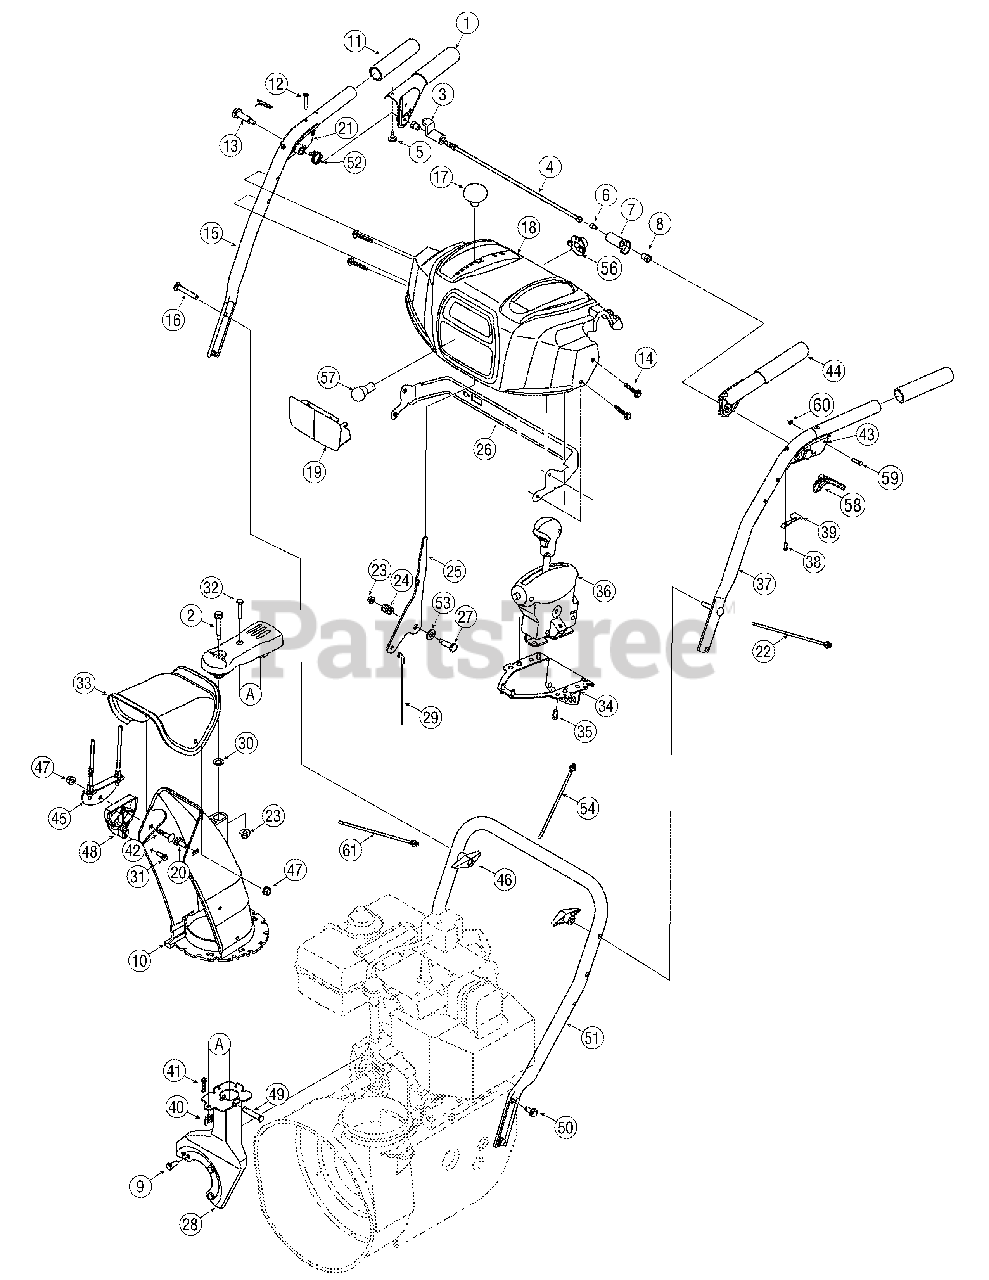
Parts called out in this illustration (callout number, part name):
1	Handle Engagement Assembly RH
2	Flange Shoulder Screw
3	Lock Plate
4	Pivot Rod
5	Rubber Bumper
6	Screw, 1/4-20 x.375
7	Clutch Lock Cam
8	Shoulder Nut, 1/4-20
9	Hex Screw, 5/16-24 x .750
10	Lower Chute
11	Handle Grip
12	Screw, #10-24 x 0.375
13	Shoulder Screw, 1/4-20 x 1.345
14	Screw, 1/4-20 x 1.625
16	Carriage Screw, 5/16-18 x 2.25
17	Shift Knob
18	Handle Panel (Includes Ref. #19)
20	Carriage Bolt, 5/16-18 x 1.0
21	Handle Clutch Lock RH Assy
22	Cable Tie
23	Flange Lock Nut, 1/4-20
24	Compression Spring
27	Shoulder Screw
28	Support Bracket
29	Speed Selector Cable
30	Flat Washer, .25 x .630 x .0515
31	Hi-Lo Screw, 1/4-15 x .75
32	Hex Screw, 1/4-20 x 1.50
33	Upper Chute
35	Hi-Lo Screw, 1/4-15 x 0.5
36	4 Way Chute Control Assembly Service Kit
38	Screw, #8-16 x 0.50
39	Clutch Lock Spring
40	Wing Nut, 1/4-20
41	Bow Tie Cotter Pin
42	Carriage Bolt, 5/16-18 x 1.50
43	Handle Clutch Lock LH Assy
44	Handle Engagement Assembly LH
46	Wing Knob
47	Flange Lock Nut, 5/16-18
48	Chute Tilt Cable Guide
49	Clevis Pin
50	Screw, 5/16-18 x 0.75
52	Torsion Spring
53	Flat Washer
54	Cable Tie
56	Light Socket
57	Lamp
58	Steering Control
59	Pin, 3/16
60	E-Ring
